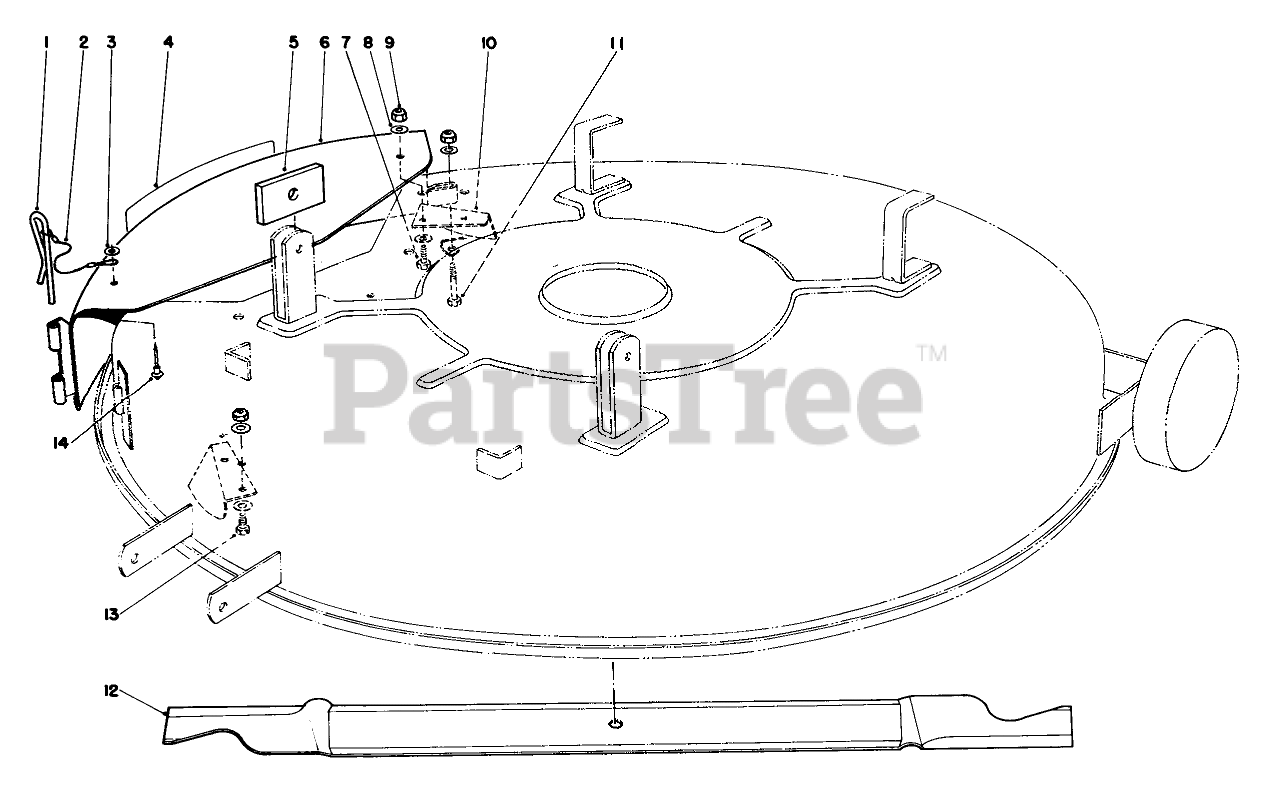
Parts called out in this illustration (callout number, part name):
1	PIN-LOCKING, CHUTE
2	LANYARD
3	WASHER-PLAIN
4	COVER DECAL
5	SPACER
6	Cover-Mulcher Assembly (Incl. Ref. #14 & 14)
7	SCREW-HH
8	WASHER-PLAIN
9	NUT-LOCK, NI
10	KICKER B
11	SCREW-HH
12	Blade
13	SCREW-HH
14	RIVET-BLIND
